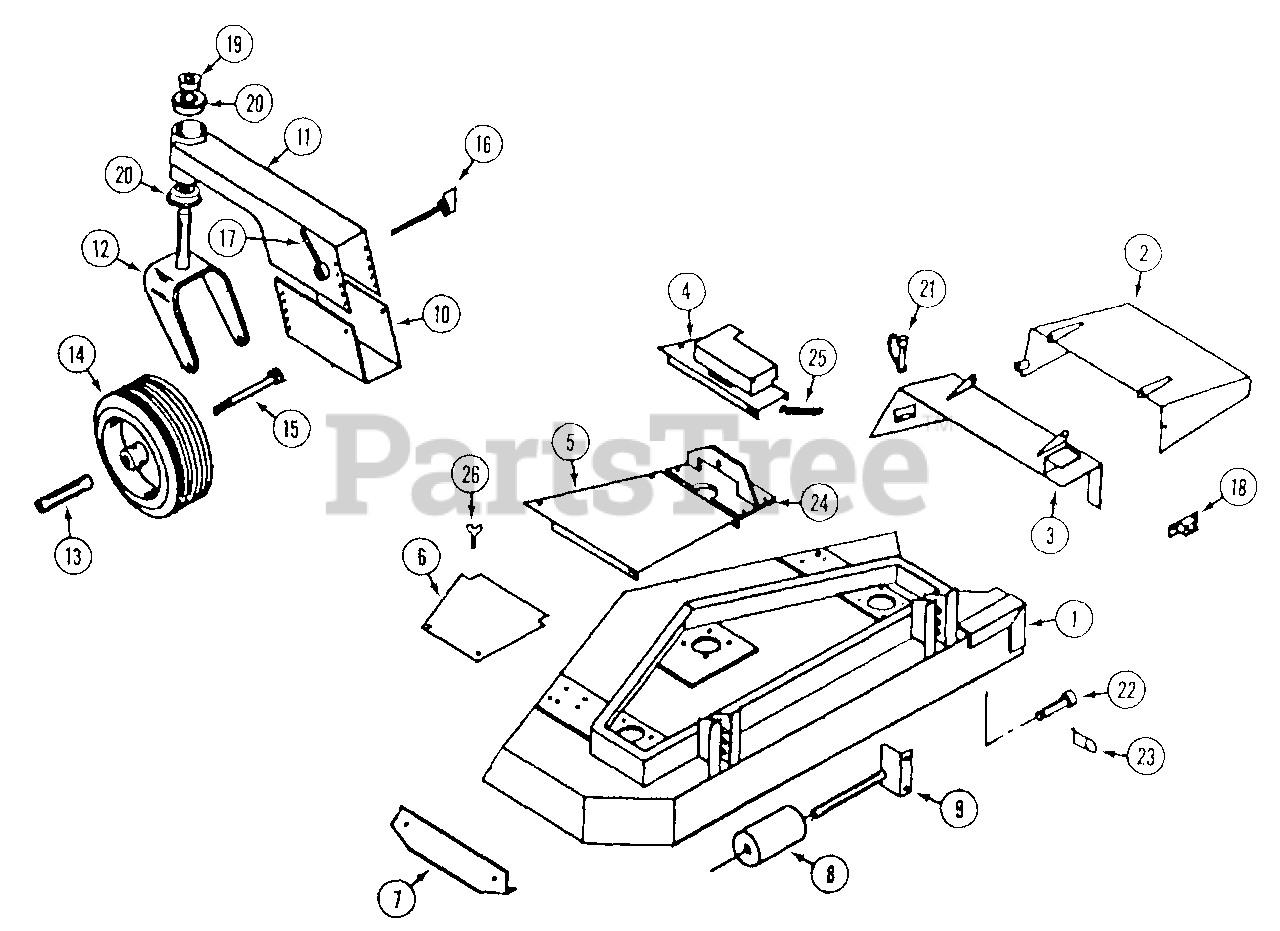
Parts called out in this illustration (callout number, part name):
1	DECK - 42"
2	CHUTE - foot guard
3	MOUNT - foot guard
4	COVER - pulley
5	COVER - center
7	SHOE - skid L.H.
8	ROLLER - anti-scalp
9	SHAFT - roller
10	BRACKET - gauge wheel mount
11	MOUNT - gauge wheel
12	FORK
13	AXLE wheel
14	WHEEL - gauge
15	BOLT - 1/2"-13 x 6-1/2"
15	BOLT - axle
17	NUT - gauge wheel handle
18	BREAKER - circuit 10 amp
19	COLLAR - set 1"
21	PIN - "fas-tatch"
23	PIN - cotter, hair
24	MOUNT - deck
